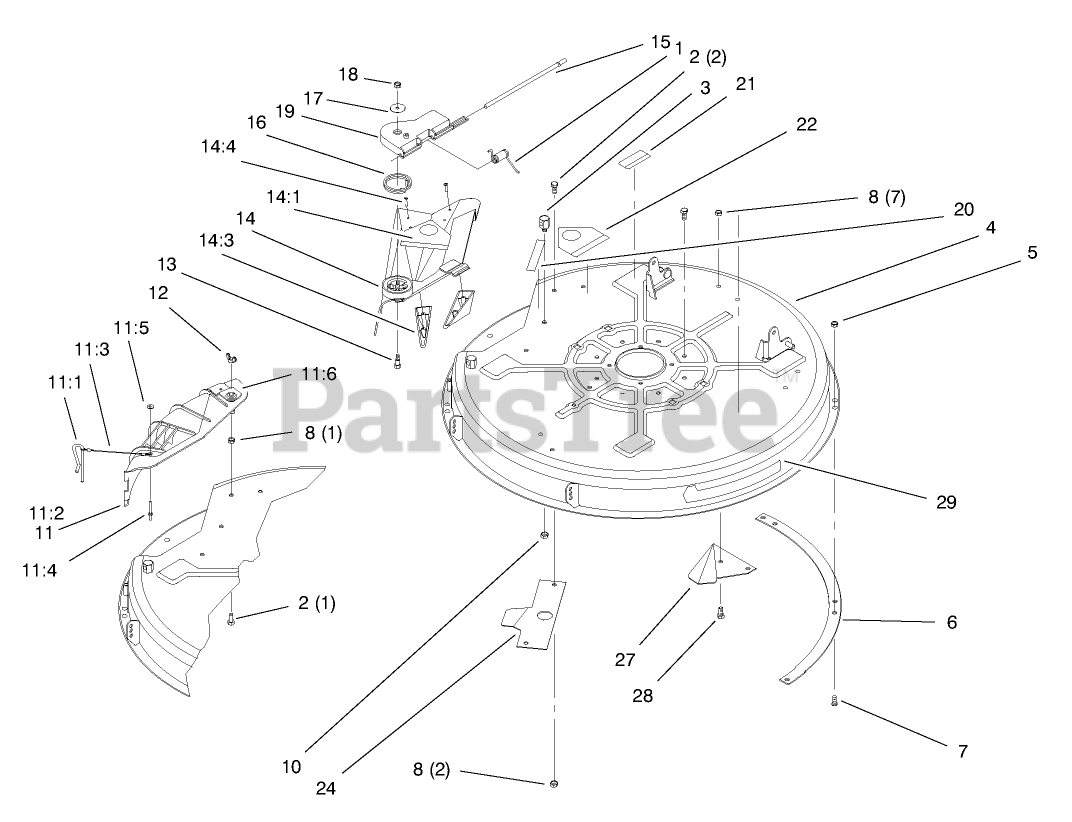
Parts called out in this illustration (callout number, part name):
1	SPRING-TORSION
2	SCREW-HH
3	POST-PIVOT
4	Deck Wa 32" Lt
4	DECK ASM
5	NUT-LOCK, NI
6	RING-DECK
7	SCREW-PPH
8	NUT-LOCK, NI
11:1	PIN-LOCKING, CHUTE
11:3	LANYARD
11:4	RIVET-BLIND
11:5	WASHER-PLAIN
12	NUT-WING
13	BOLT-SHOULDER
14	32 INCH DEFLECTOR ASM
14:1	DECAL-DANGER
14:3	KICKER
14:4	SCREW-PPH
15	ROD-HINGE, DEFLECTOR
16	SPRING-TORSION
18	NUT-LOCK, NI
19	PIVOT-HINGE, DEFLECTOR
20	DECAL-DANGER
21	DECAL-WARNING
22	DECAL-DANGER
24	RAMP-DEFLECTOR
28	SCREW-HH
